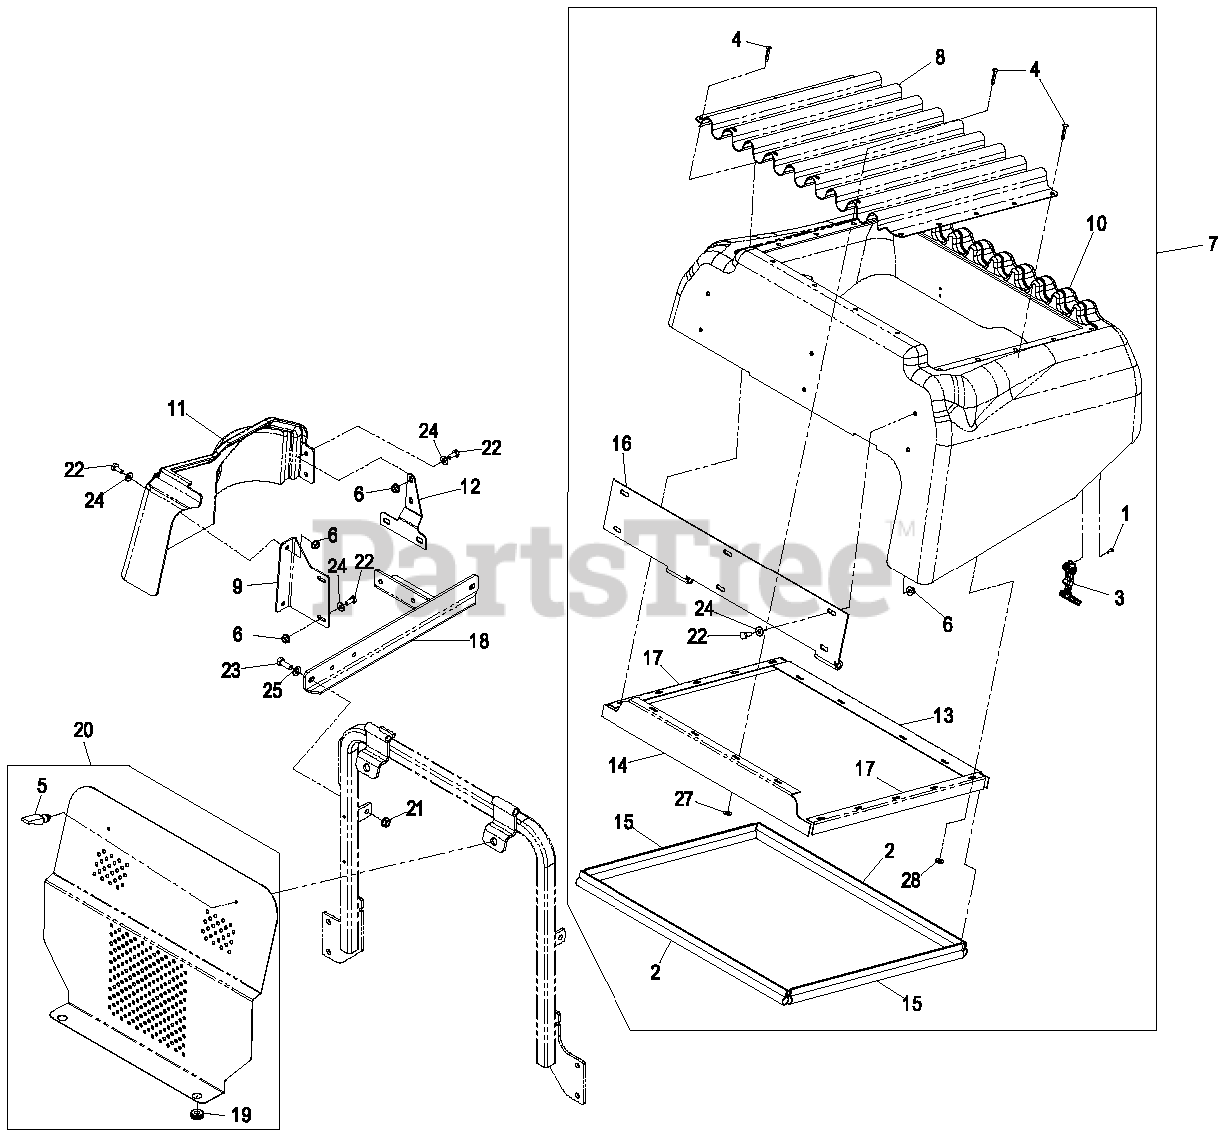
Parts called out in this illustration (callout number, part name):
2	SEAL-TRIM
3	LATCH-RUBBER
5	LATCH-SWELL
8	SCREEN, RADIATOR
9	BRACKET,FRONT COVER
11	PANEL, SIDE
12	BRACKET,REAR COVER
13	MOUNT,SEAL REAR
14	MOUNT,SEAL FRONT
15	SEAL,TRIM 17.1
16	WLD, HINGE
17	MOUNT,SEAL SIDE
18	ASM,AIR CLNR BRKT W/DECAL
19	GROMMET
20	ASM,PANEL W/ DECALS LXS L
22	SCREW-HH
23	SCREW-HH
24	WASHER-FLAT
25	WASHER-PLAIN
27	WASHER-SPRING
28	WASHER-FLAT
